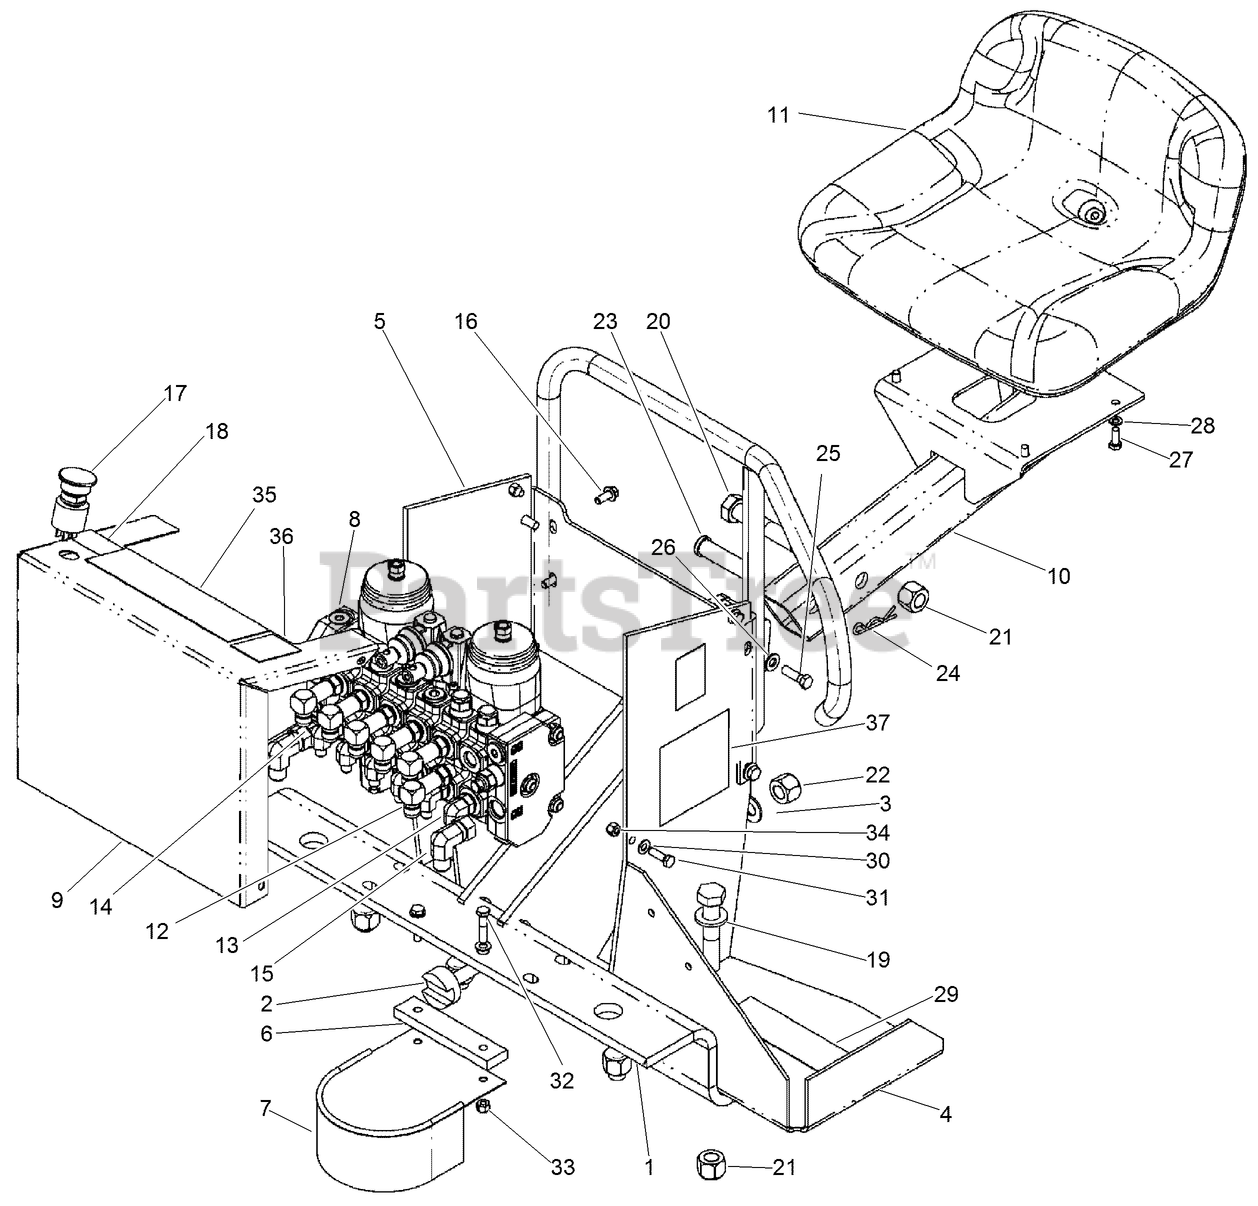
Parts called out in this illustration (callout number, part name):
1	WELDMENT-Angle, Swg Cyl Mtg
2	GUIDE-Rack.
3	WASHER-FLAT
4	WELDMENT-Guard, LH Foot
5	WELDMENT-Guard, RH Foot
6	BAR-Spacer
7	WELDMENT-Cover, Swing Gear
8	VALVE-Backhoe, w/Special Low Leak Spools
9	COVER-Valve
10	POST-Seat, Backhoe
11	SEAT-BLACK, LOW-BACK
13	ELBOW-90 Adj 37FL, 3/8 x 1/2 Tube
14	CONNECTOR-Str Thd 5/8, 37FL-ORB 5/8
15	ELBOW-90 Swivel 37FL 5/8 Tube
16	SCREW, METRIC FLANGE w/BODY - M8 x 20
17	BUTTON-E-STOP
18	DECAL-Engine Shut-Off
19	WASHER-Flat
20	BOLT-Hex Hd 0.750 x 3.75 GR8 ZND
21	NUT-Prev Trq 3/4 GRC CAD Direct
22	NUT-Hex Lock 5/8-18 CAD GRD A
23	PIN-Seat Lock
24	PIN-HAIR COTTER, INT
25	BOLT
26	WASHER-FLAT
28	WASHER-Lock, 5/16 inch
29	STRIP-Anti-skid, Backhoe Access Steps
30	WASHER-Flat 5/16 HT
31	SCREW-HH
32	BOLT-Hex, 5/16 NC x 1-1/2 inch
33	NUT-Prev Trq 5/16 GRA CAD NONDIR
34	NUT-HEX
35	DECAL-Backhoe Control Pattern
36	DECAL-Read Operators Manual
37	DECAL-Warning, Lifting with Backhoe
